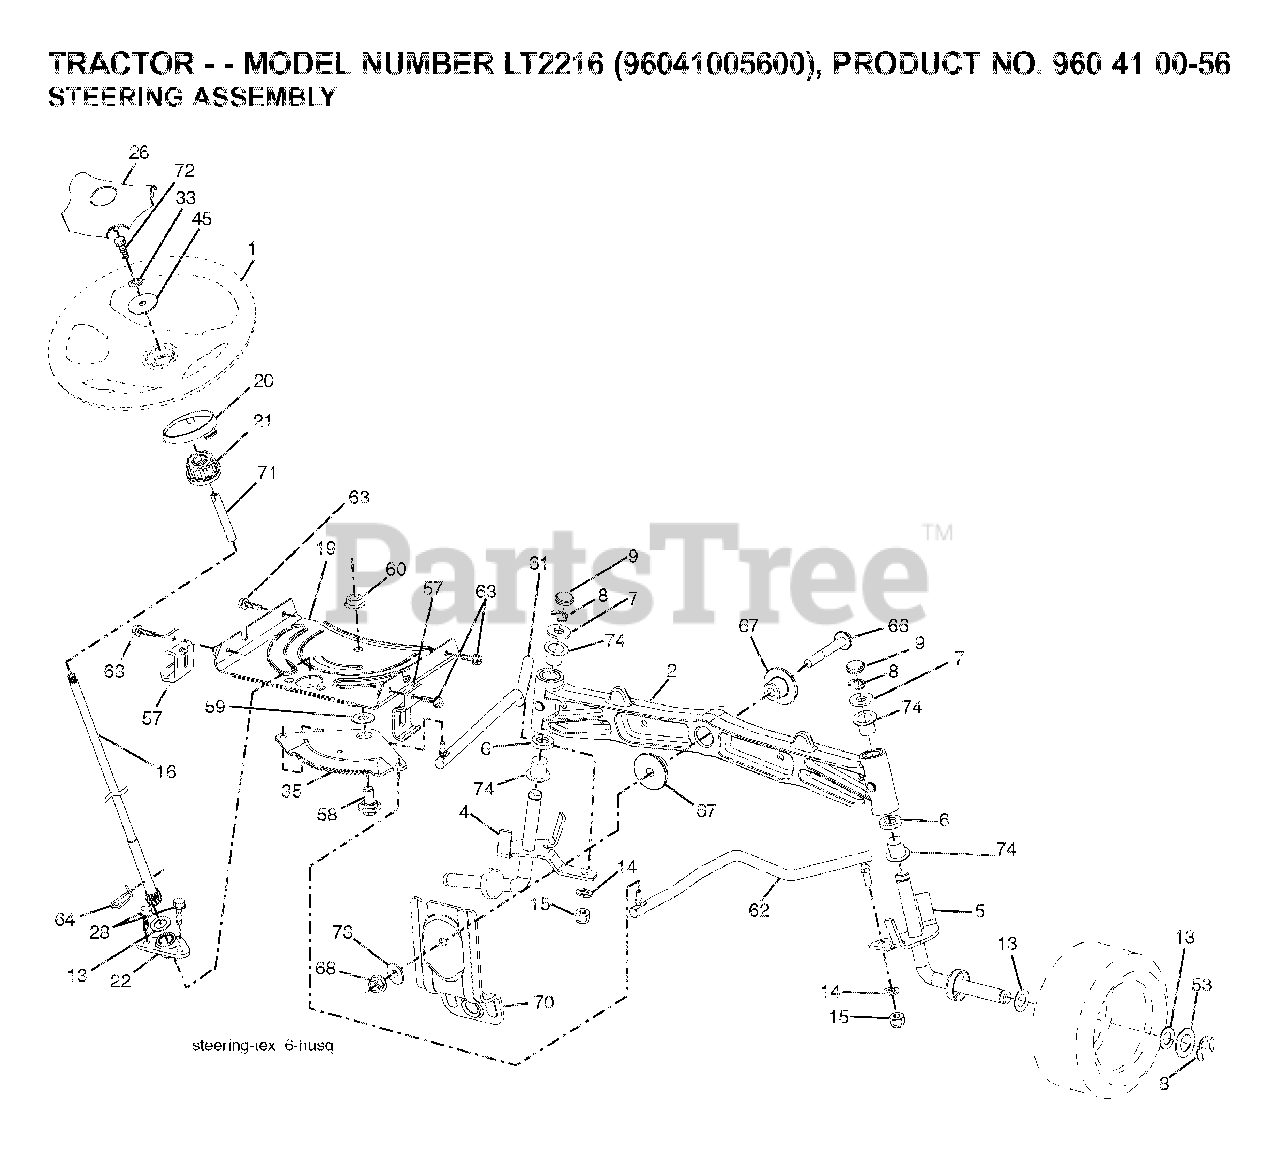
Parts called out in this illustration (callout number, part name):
2	AXLE.HALF.ASM.WELDED
4	SPINDLE.WELDED.LH.15"TEX
5	SPINDLE.WELDED.RH.15"T
8	RING CLIP
9	CAP.SPINDLE
14	WASHER, LOCK 3/8
15	NUT CROWNLOCK 3/8-24
16	SHAFT STEERING
19	PLATE.STEER.DDL.NLT/NG
20	BOOT STEERING BLACK
21	ADAPTER, WHEEL STNG..
22	BUSHING.ASM.STEERING.A
26	INSERT.CAP.STRG.WH.BLACK
28	SCREW, 3/8-16X3/4
33	LOCKWASHER
35	GEAR.SECTOR.PLATE.DDL.
45	WASHER.11/32
53	WASHER.HARDENED
57	BRACKET.UPSTOP.TEX
58	BOLT.SHOULDER.SECTOR.P
59	WASHER.THURST.SECTOR.S
60	NUT FLANGE LOCK 5/8-11
61	DRAGLINK.LH.BALLSTUD.D
62	DRAGLINK.RH.BALLSTUD.D
63	SCREW
64	RETAINER.CLIP.SPRING.S
66	BOLT HEX FGHD 7/16-14 X 3 SERR
67	BUSHING.PM.FRONT AXLE
68	NUT.LOCK.FLANGE.7/16
70	BRKT.DECK.SUSPENSION.F
71	SHAFT EXTENSION STEERING
72	BOLT YT
73	WASHER.1.5X.505X.118
74	BRNG T
